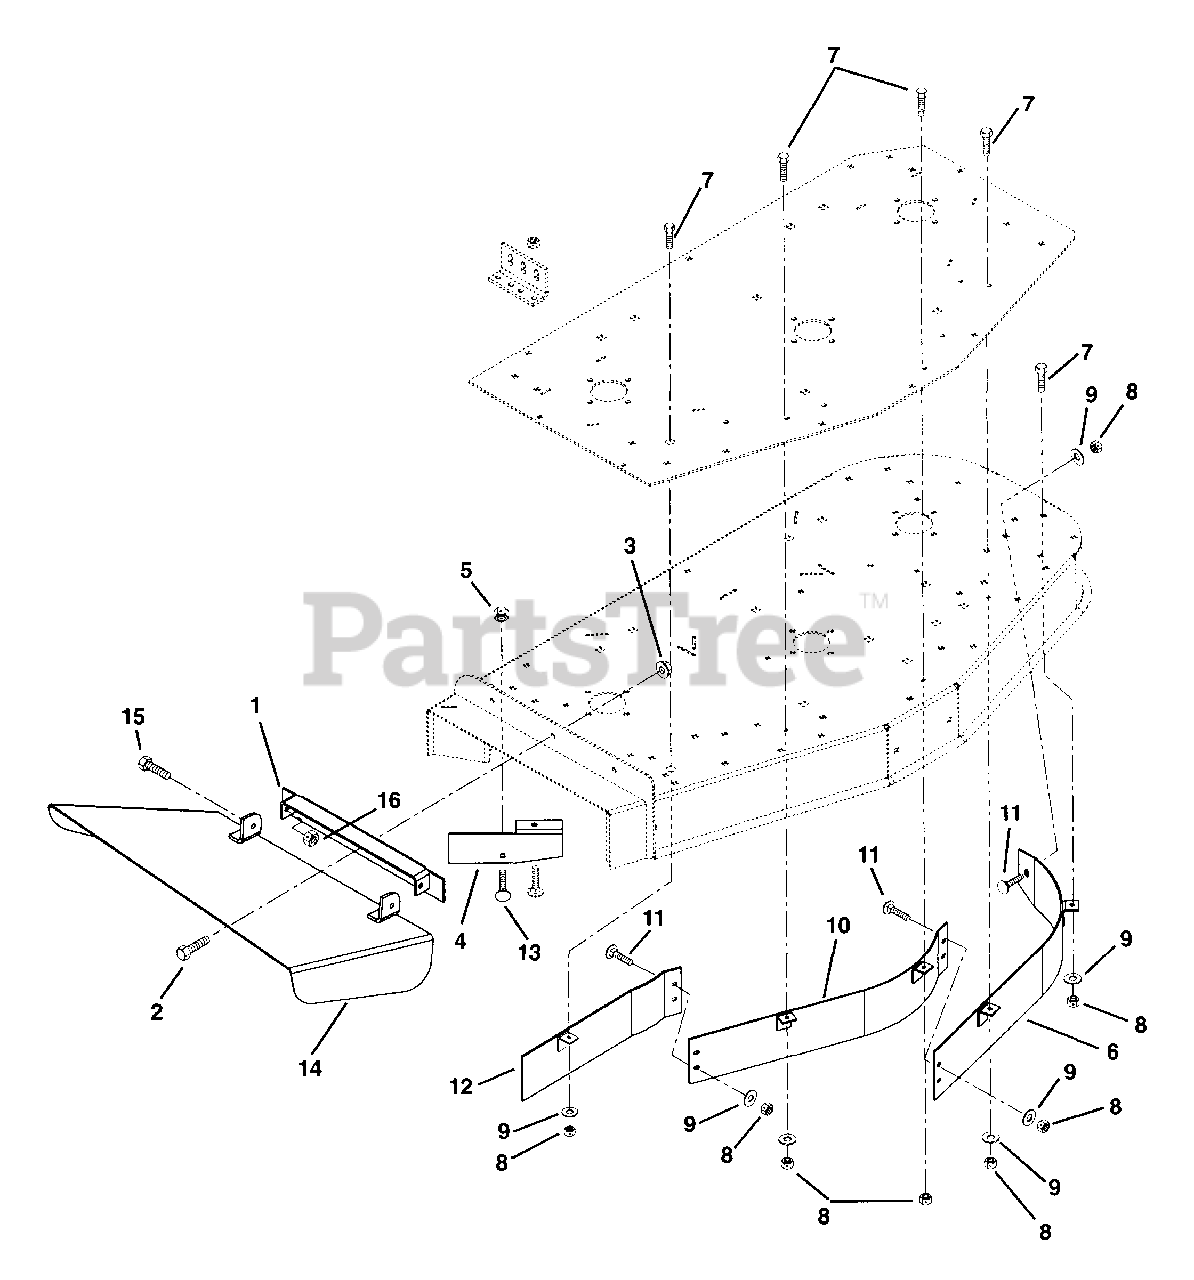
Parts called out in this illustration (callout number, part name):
1	Weldment, Discharge Chute Bracket
2	Bolt-Hex .38-16 x .75 Grade 5
3	Nut-Locking-Flange .38-16
4	Deflector
5	Nut-Locking-Center .38-16
6	Weldment, 50" Left Hand Baffle-Upper
7	Bolt-Hex .31-18 x 1.00 Grade 5
8	Nut-Locking-Nylon .31-18
9	Washer-Flat-Steel .312 x .734 x .065
10	Weldment, 50" Center Baffle-Up
11	Bolt-Round Head Square Neck .31-18 x 1.00 Grade 5
12	Weldment, 50" Right Hand Baffle-Upper
13	Bolt-Round Head Square Neck .38-16 x 1.00 Grade 2
14	Weldment, Discharge Chute 50"
15	Bolt-Hex .38-16 x 1.00 Grade 5
16	Nut-Locking-Center .38-16
